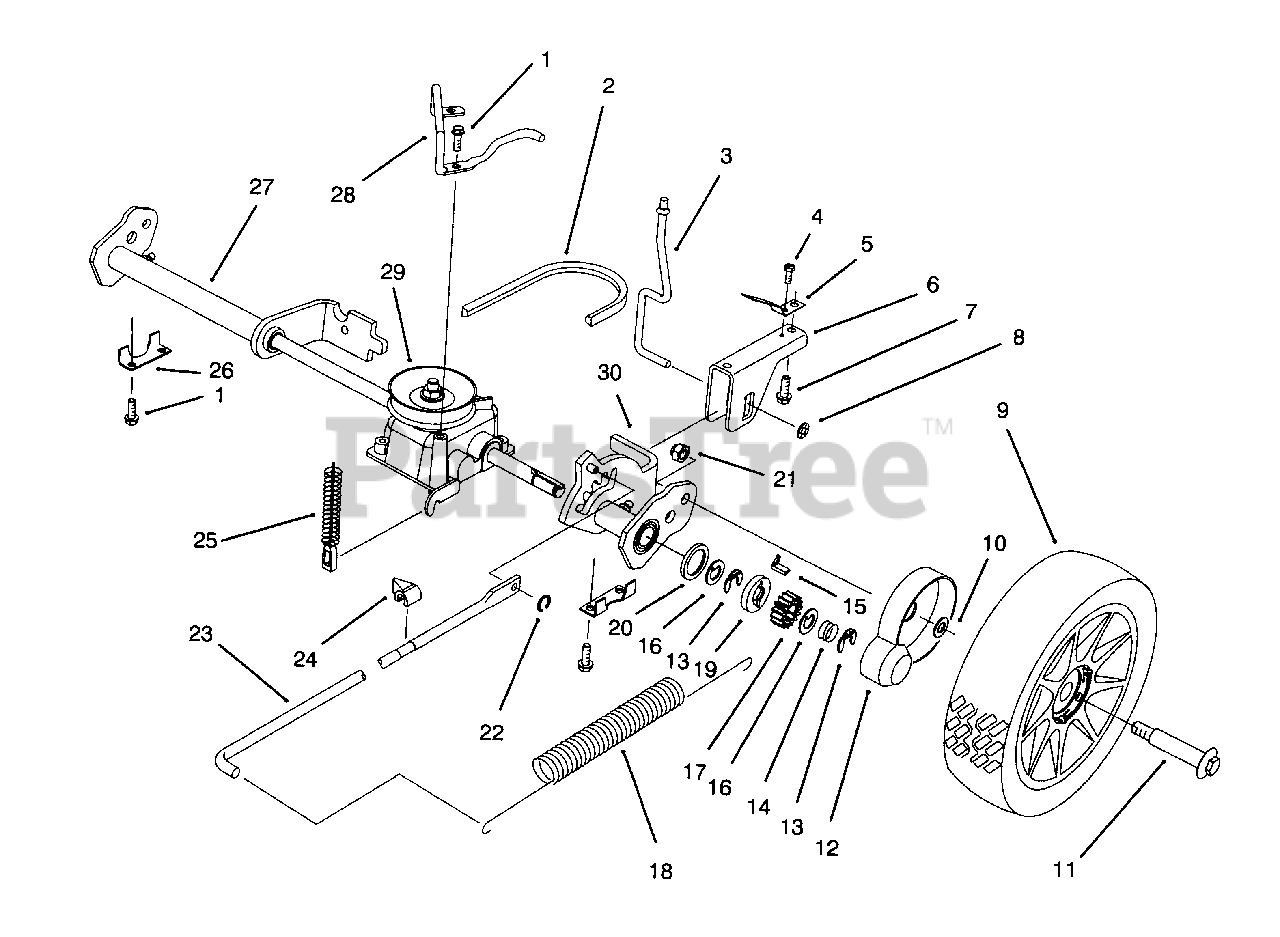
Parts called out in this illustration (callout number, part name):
1	Screw-Tapping
2	V-Belt-Gear Case
3	Rod-Trigger
4	Screw-Tapping
5	Spring-Trigger Retainer
6	Saddle-H.O.C.
9	Wheel & Tire Assembly
10	Spacer-Wheel
11	Bolt-Shoulder
12	Cover-Wheel
13	Ring-Retaining
14	Spring-Compression
15	Key-Rocking L.H.
16	Washer-Thrust Keyed
17	Gear-Pinion
18	Spring-Counter balance
20	Ring-Friction
21	Nut-Lock
22	Ring-Grip
23	Rod-Link
24	Indicator-H.O.C.
25	Spring-Compression
26	Plate-Securing Rear
27	Arm-R.H. Pivot
28	Retainer-Belt
29	Case-Gear
30	Arm-L.H. Pivot
